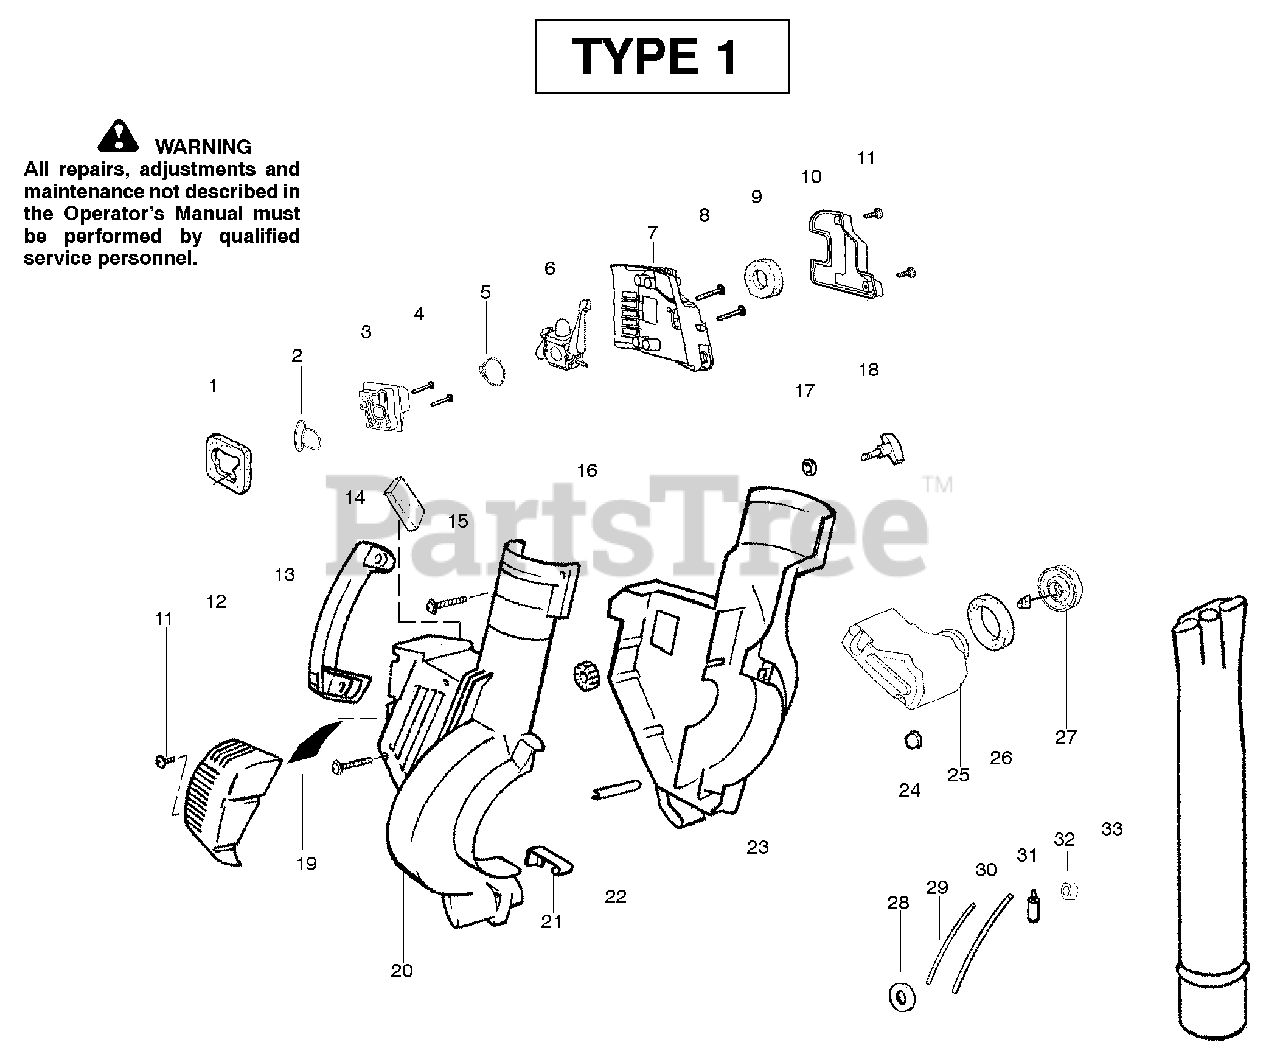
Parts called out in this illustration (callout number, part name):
1	Air Dam (kit)
2	Gasket-Adapter (kit)
3	Carburetor Adaptor
5	Gasket-Carburetor (kit)
6	Kit-Carb Ass’y. Zama-(C1Q-W11C)
6	Kit-Carb Ass’y. Walbro-(WT-606)
10	Cover-Air Filter
12	Guard-Muffler
14	Foam - 71.12mm (kit)
18	Knob-Tube Clamp
19	Reflector-Heat (kit)
20	Housing-Right
21	Spring-Cover Latch
22	Guide-Starter Rope
24	Isolator-Crankcase
25	Assy-Fuel Tank
26	Gasket-Fuel Tank
27	Fuel Cap w/Retainer
28	Grommet-Shroud
29	Kit-Line Carb/Purge
30	Kit-Line Tank/Purge
31	Assy-Fuel Pick-up
32	Grommet-Fuel line (kit)
